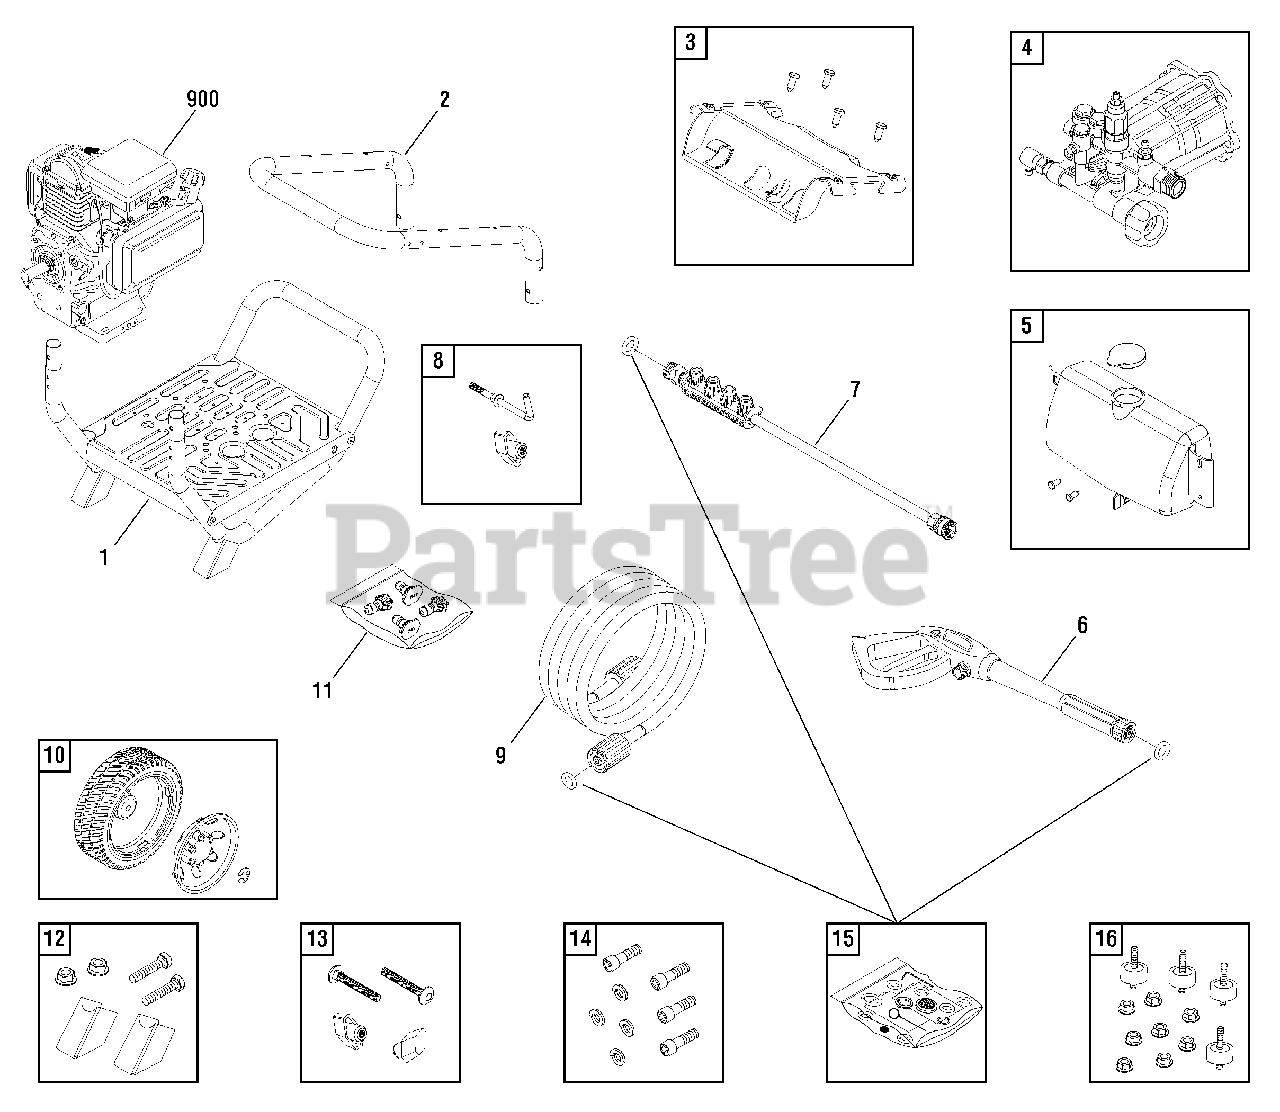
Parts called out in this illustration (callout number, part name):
6	GUN
9	HOSE
11	KIT-QC NOZZLES
12	MOUNT-VIBRATION
13	KIT-HARDWARE HANDLE
14	KIT-HARDWARE PUMP MOUNTING
16	KIT-VIBRATION MOUNT
900	** ENGINE
